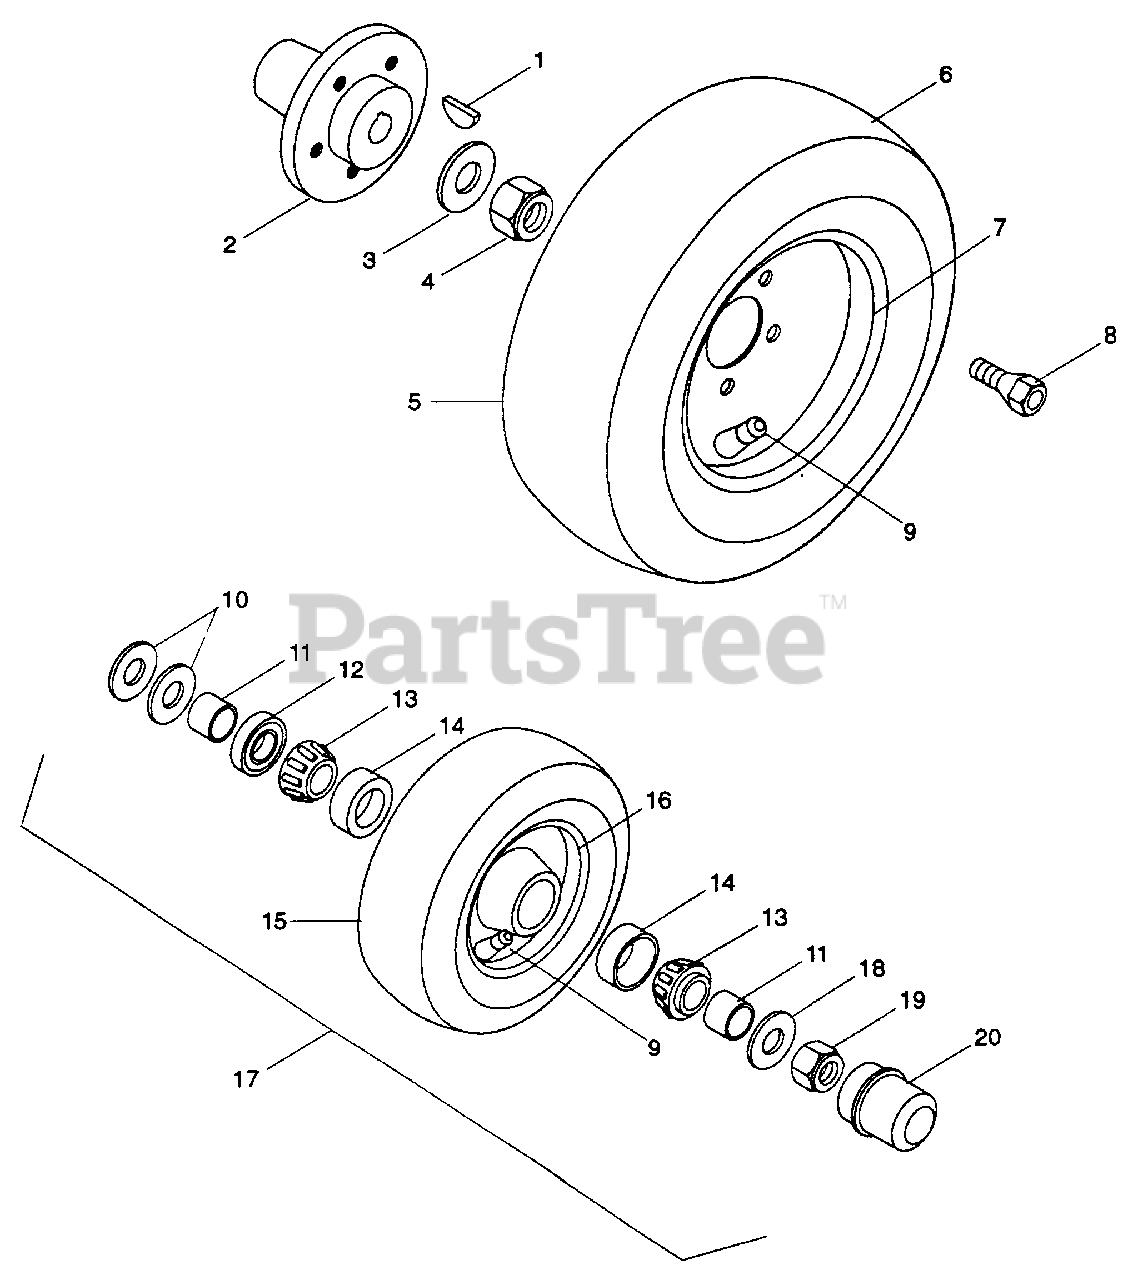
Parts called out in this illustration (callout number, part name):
1	KEY, WDRF .25 X 2.13 5 FT
2	HUB, TAPERED 4-WHL
3	WSHR-FL-STL .813 X 2.000 X .148
4	NUT-LK-NYL INSR .75-10 PL
5	TIRE-REAR
5	T/WHL ASS'Y 23 X 10.5-12
6	TIRE, REAR 23 X 8.50-12
6	TIRE, REAR 23 X 10.50-12
7	WLDMT, RIM
8	BLT .44-20 X 1.0
9	VALVE STEM ASS'Y
10	WSHR-FL-STL .813 X 1.37 X .100
11	SPACER
12	SEAL 1.206 X 1.785 X .486
13	BRG/CONE .750 X .61
14	BRG/CUP 1.781 X .475
15	TIRE, FRONT 16 X 6.50-8
15	TIRE, FRONT 16 X 7.50-8
16	WELDMENT, RIM
17	TIRE, FRONT 16 X 6.50-8
17	T/WHL ASSY 16 X 7.50-8
18	WSHR-FL-STL .656 X 1.312 X .095 PL
19	NUT-LK-NYL .625-11 PL
20	DUST CAP
